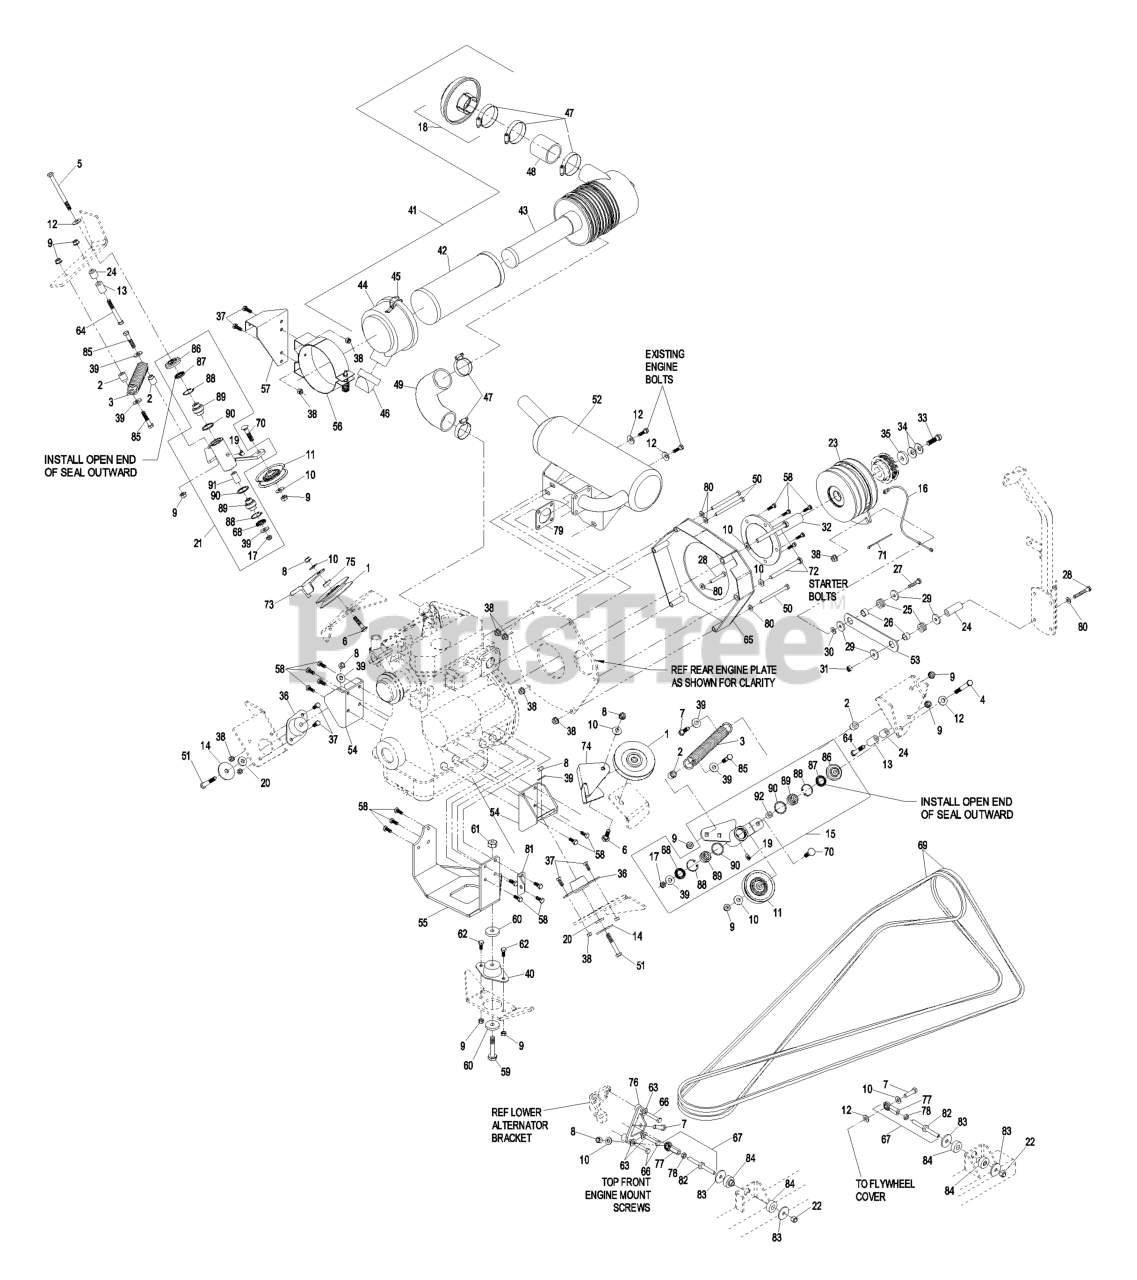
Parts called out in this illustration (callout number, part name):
2	SPACER-TIGHTENER, BELT
3	SPRING-EXTENSION
4	SCREW-HH
5	SCREW-HH
6	BOLT-CARR, SHORT NECK
7	SCREW-HH
8	NUT-LOCK, NI
9	NUT-HHF, WHIZ
10	WASHER-FLAT
12	WASHER-BELLEVILLE
13	SPACER-HYDRO CONTROL, LH
14	WASHER-FLAT
15	KIT,MULE IDLER XP LH
16	KIT,CLUTCH JUMPER HARNESS
18	HOOD-CLEANER, 2" AIR INTA
19	FITTING-GREASE, 90 DEG
21	KIT,MULE IDLER RH XP
22	NUT-LOCK
24	SPACER-STRAP, CLUTCH
25	GROMMET
27	SCREW-HH
28	SCREW-HH
30	WASHER-FLAT
31	NUT-LOCK, NI
32	SHAFT-STUB
33	SCREW-HH
34	WASHER-SPRING
35	WASHER-CLUTCH
36	ISOLATOR-SIDE
37	SCREW-HH
39	WASHER-FLAT
40	ISOLATOR-REAR
41	FILTER-AIR
42	FILTER-AIR
43	FILTER-AIR, SAFETY
44	COVER-FILTER, AIR
45	CLIP-CLEANER, AIR
46	VALVE-EJECTOR, DUST
47	CLAMP-HOSE
48	HOSE-INTAKE
50	SCREW-HH
51	BOLT-CARR
52	MUFFLER KIT
53	STRAP-CLUTCH / BRAKE
54	LH AND RH ENGINE MOUNT AS
55	REAR ENGINE MOUNT ASM
56	BRACKET-FILTER, AIR
57	MOUNT-CLEANER, AIR
58	SCREW-HH
59	SCREW-HH
60	WASHER-THRUST
61	NUT-LOCK, NI
62	SCREW-HH
63	WASHER-SPRING
64	SCREW-HH
65	COVER-FLYWHEEL
66	SCREW-HH
67	BALL JOINT LINK ASM
68	SEAL-LIP, DOUBLE
69	BELT-V
70	SCREW-CARR
71	TIE-PLASTIC
72	SCREW-HH
73	GUARD-BELT SHEAVE, RH
74	GUARD-BELT SHEAVE, LH
75	SPACER-BRACKET, GUIDE
76	BRACKET-ENGINE, FRONT
77	JOINT-BALL, END
78	NUT-HJ
79	GASKET-MUFFLER
80	WASHER-PLAIN
81	BRACKET-GROUND
82	LINK,REAR A-T AXIAL
84	ISOLATOR-LINK
85	SCREW-HH
86	GUARD-TOP
87	SEAL-LIP, SINGLE
88	RING-SNAP
89	BEARING-SPHERICAL
92	BUSHING-LEVER, LIFT
